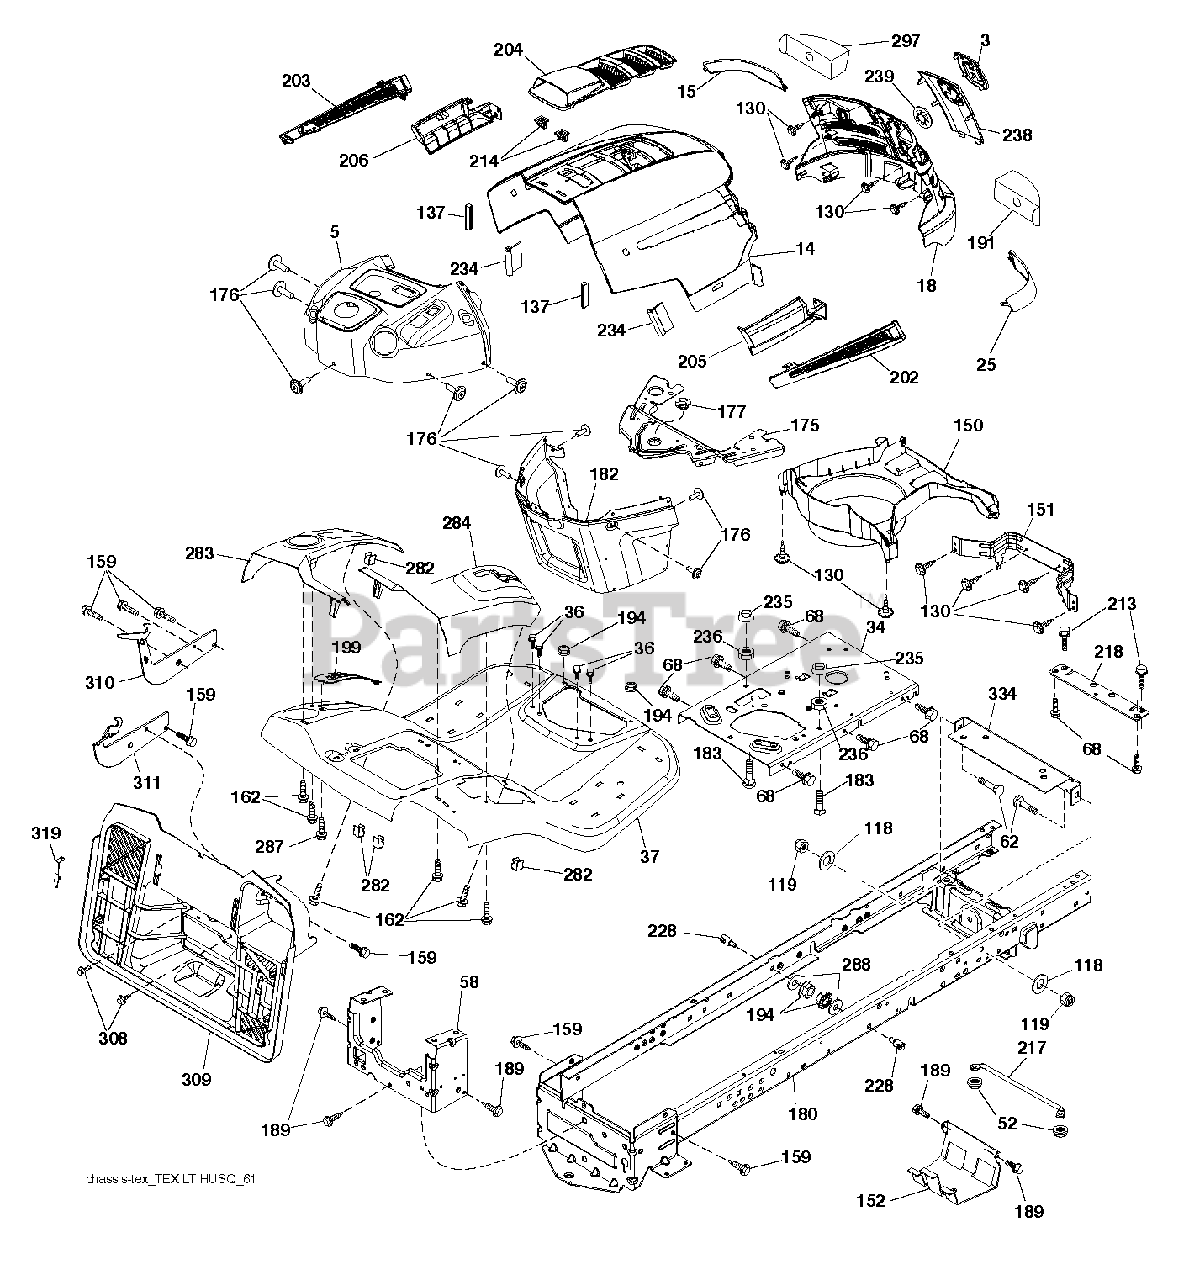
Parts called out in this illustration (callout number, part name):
3	LOGO.HUSQ.GT.LT.CROWN.H
5	SUBASM.DASH.UPPER.HLT.498
14	HOOD.HUSQVARNA.LT.ORANGE
15	LENS.HUSQVARNA LT.RH
18	GRILLE.SVC.HUSQVARNA.GREY
25	LENS.HUSQVARNA LT.RH
34	PLATE.ENGINE.10GA.CRD.GENII
36	SCREW 5/16"
37	FENDER.TEX.SRD.CRD.BASE
52	LOCKNUT
58	DRAWBAR UPPER 2PC SMALL FENDER
62	BOLT D
68	SCREW LT
118	WASHER
130	SCREW.#10 X 0.750.BOS
137	BUMPER DASH
151	BRACKET PIVOT
152	SHIELD.BROWNING.W/TEX
159	SCREW, 3/8-16X3/4
162	SCREW.HI-LO.CONSOLE
175	CROSSMEMBER
176	SCREW.#10-24X5/8.RN.QU
177	BUSHING STEERING
180	CHASSIS.WLDMNT.14GA.2PC.18".TI
182	DASH.LOWER.PREDATOR LT
183	BOLT.5/16-18X1-1/4 FULL THD
189	SCREW
191	INSERT.REFLECTIVE.RH.
194	NUT LOCK HEX FLANGE 5/16-18
199	PLATE DECK LIFT
202	VENT.SIDE.HUSQVARNA.LT.RT
203	VENT.SIDE.HUSQVARNA.LT.LFT
204	SUBASM.TOP.VENT.HUSQ.LT
205	SKIRT.SIDE.HUSQVARNA.LT.RT
206	SKIRT.SIDE.HUSQVARNA.LT.LEFT
213	BOLT
214	CLIP.RETAINER.TINNER.
217	ROD.PIVOT.HOOD
218	X-PIECE.HOOD.STOP.NON/
228	STUD.FASTNER.W/ANTI-ROTATE
234	BUMPER.HOOD.TEX.HUSQVARNA
235	SPACER FENDER
236	NUT.CENTERLOCK.5/16-
238	TRIM.HUSQ LT.668
282	CLIP.RETAINER.CONSOLE.LT.HUSQ
283	CONSL.DECKLIFT.LH.SRD.TEX.CRD
284	CONSL.SHFT.PEDAL.RH.SRD.TEXCRD
287	SCREW 1/4X20
288	WASHER
297	INSERT REFLECTIVE
308	BOLT, 5/16-18 X 1 3/4
309	BACKPLATE.BAGGER.V2.SRD
310	LH.ADJUST.HANGER.BRACKET.ASM
311	RH.ADJUST.HANGER.BRACKET.ASM
319	BRACKET.ACTUATOR.BAGGER.SRD
334	BRACKET.ENGINE
